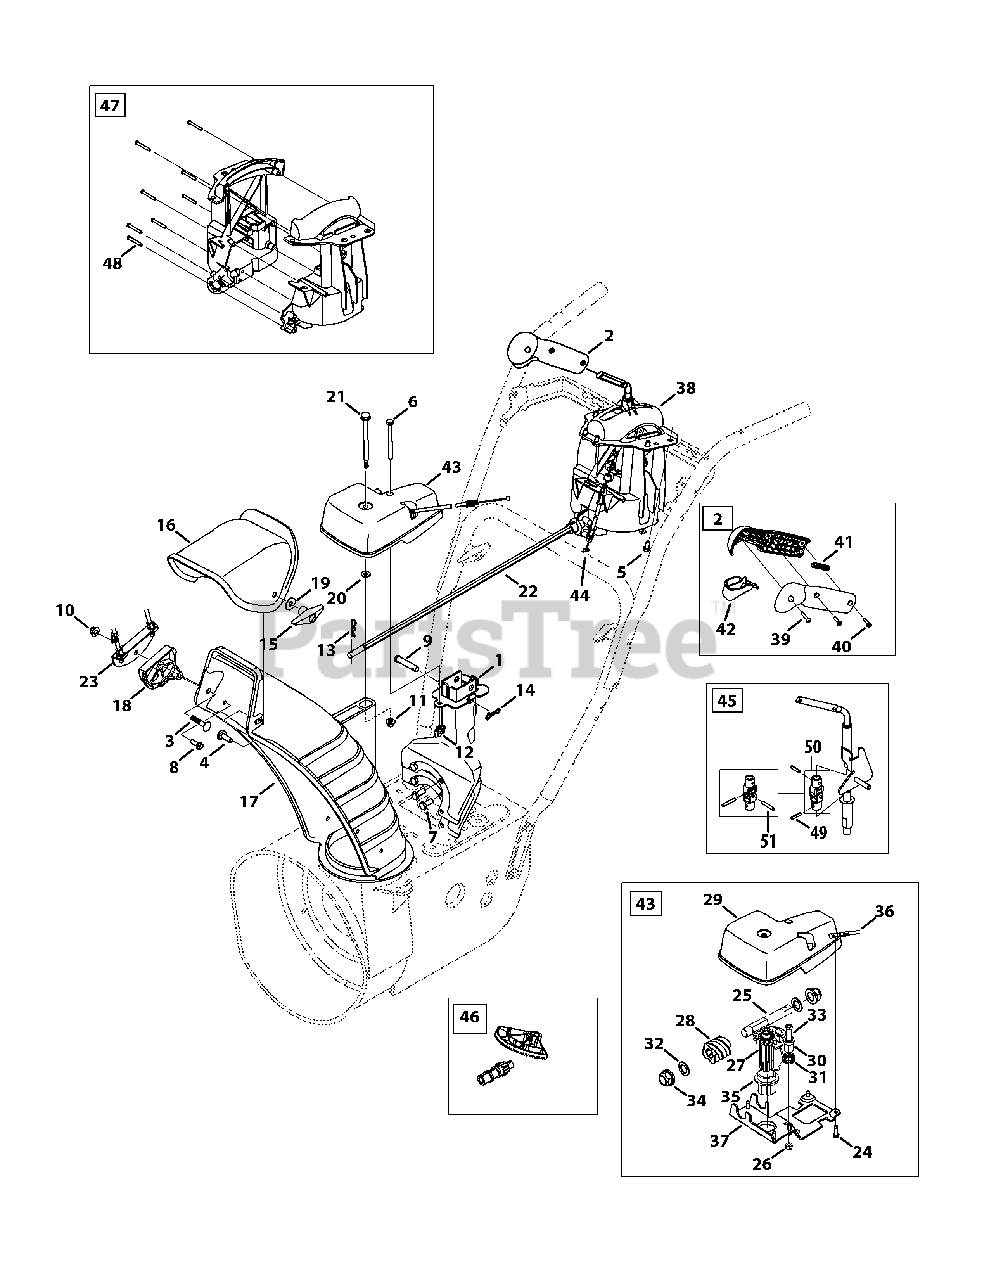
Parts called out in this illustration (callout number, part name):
1	Chute Support Bracket (small block)
2	Chute Control, 4-Way
3	Bolt, Carriage, 5/16-18 x .750, 2-Way
4	Bolt, Carrier, 5/16-18 x 1.00
5	Screw, Hi-Lo, 1/4-15 x 0.50
6	Hex Head Screw, 1/4-20 x 3.00
7	Hex Head Screw, 5/16-24 x .750
8	Screw, Hi-Lo, 1/4-15 x 0.750
9	Clevis Pin, 3/8 x 1.87
10	Nut, Flange Lock, 5/16-18
11	Nut, Flange Lock, 1/4-20
12	Wing Nut, 1/4-20
13	Internal Cotter Pin
14	Bow-Tie Cotter Pin
15	Wing Knob, 5/16-18
16	Chute, Upper, 2-Way
17	Chute, Lower
18	Cable Guide, Chute Tilt
19	Washer, Flat, .349 x .879
20	Washer, Flat, .25 x .630
21	Screw, Shoulder, .312 x 3.5 x 1/4-20
22	Chute Rod, 3/8 Hex
23	Cable Bracket
24	Screw, 12-16 x .75
25	Hex Shaft
26	Hexlock Nut, 1/4-28
27	Gear, 14 T
28	Worm
29	Gear Cover
30	Pawl Lock
31	Torsion Spring, .721 ID x .474
32	Washer, Flat, .625 x 1.0 x .067
33	Screw, Shoulder, .34 x .95 x 1/4-28
34	Hex Bearing
35	Flange Bearing
36	Cable Lock
37	Gear Bracket
38	Chute Control, 2-Way
39	Screw, #8 x 1.00
40	Screw, 8-32 x .750
41	Joystick Plug
42	Joystick Trigger
43	Chute Rotation Gearbox
44	4-Way Cable
44	Cable Clip
45	Shift Assembly, 2-Way
46	Gear Set Assembly
47	Handle Housing Assembly, 2-Way
48	Screw, #8-18 x 1.250
49	Pin, Roll
50	Block, Asm Joint
51	Pin, Roll
